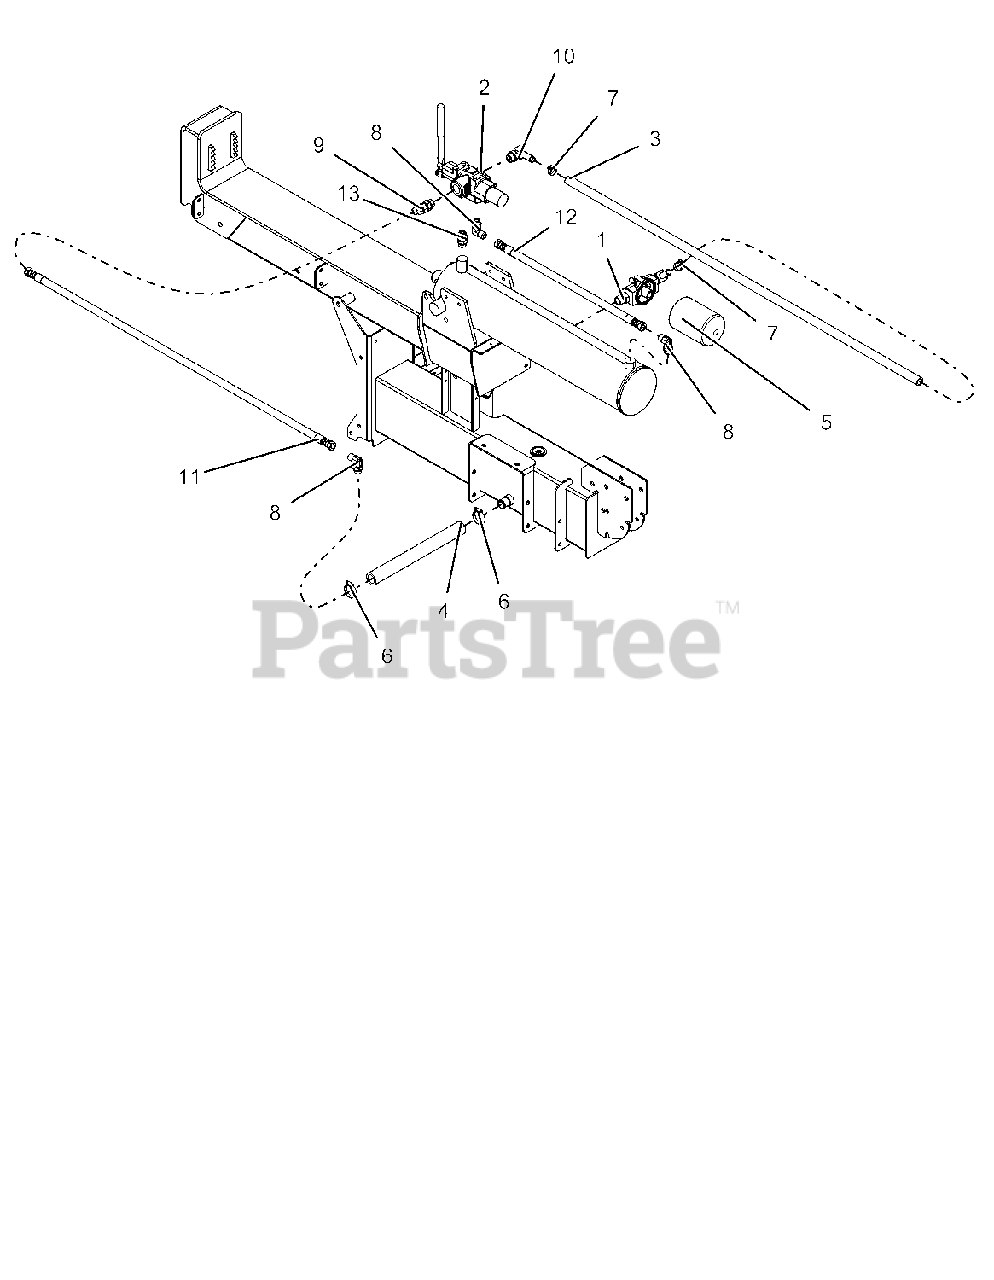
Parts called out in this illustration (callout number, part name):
1	ASM, FILTER HEAD
2	VALVE CONTROL-SPLITTER
3	HOSE,HYD RETURN 10LOLA X 53"
4	HOSE,HYD SUCTION 16G4H X 13.5
5	FILTER,HYDRAULIC OIL-NO BYPASS
6	CLAMP-HOSE 1.50X.81X1.42
7	CLAMP,.88 DIA. HOSE
8	FTG,HYD 6801-8-8
9	FTG,HYD 6802-8-10
10	FTG,HYD 4601-10-10
11	HOSE, ASM - 46"
12	HOSE, HYD - 22"
13	FTG, HYD - STR 08MAORB-08MORB
